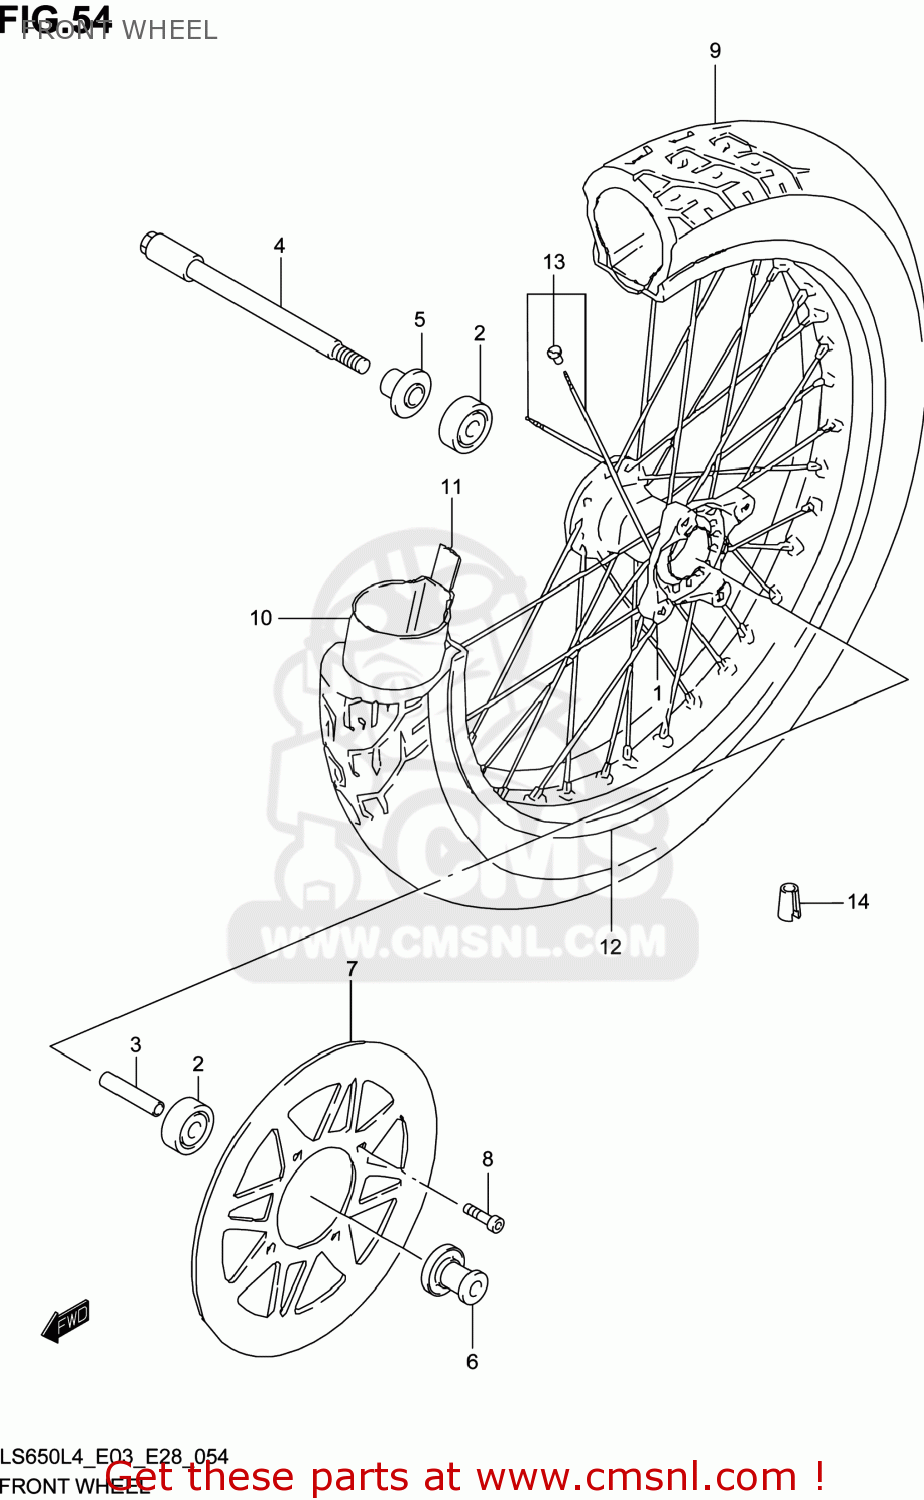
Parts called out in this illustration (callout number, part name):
1	HUB,FR WHEEL
2	BEARING
3	SPACER(15.3X21.7X56)
4	AXLE,FR
5	SPACER,FR AXLE,R
6	SPACER,FR AXLE,L
7	DISC,FR BRAKE
8	BOLT(8X25.5)
9	TIRE,FR(100/90-19 57H)
10	TUBE
11	PROTECTOR,WHL INR TUBE FR
12	RIM,FR WHEEL WM(2.15X19)
13	SPOKE SET,FR WHEEL
14	BALANCER,WHEEL(15G)
